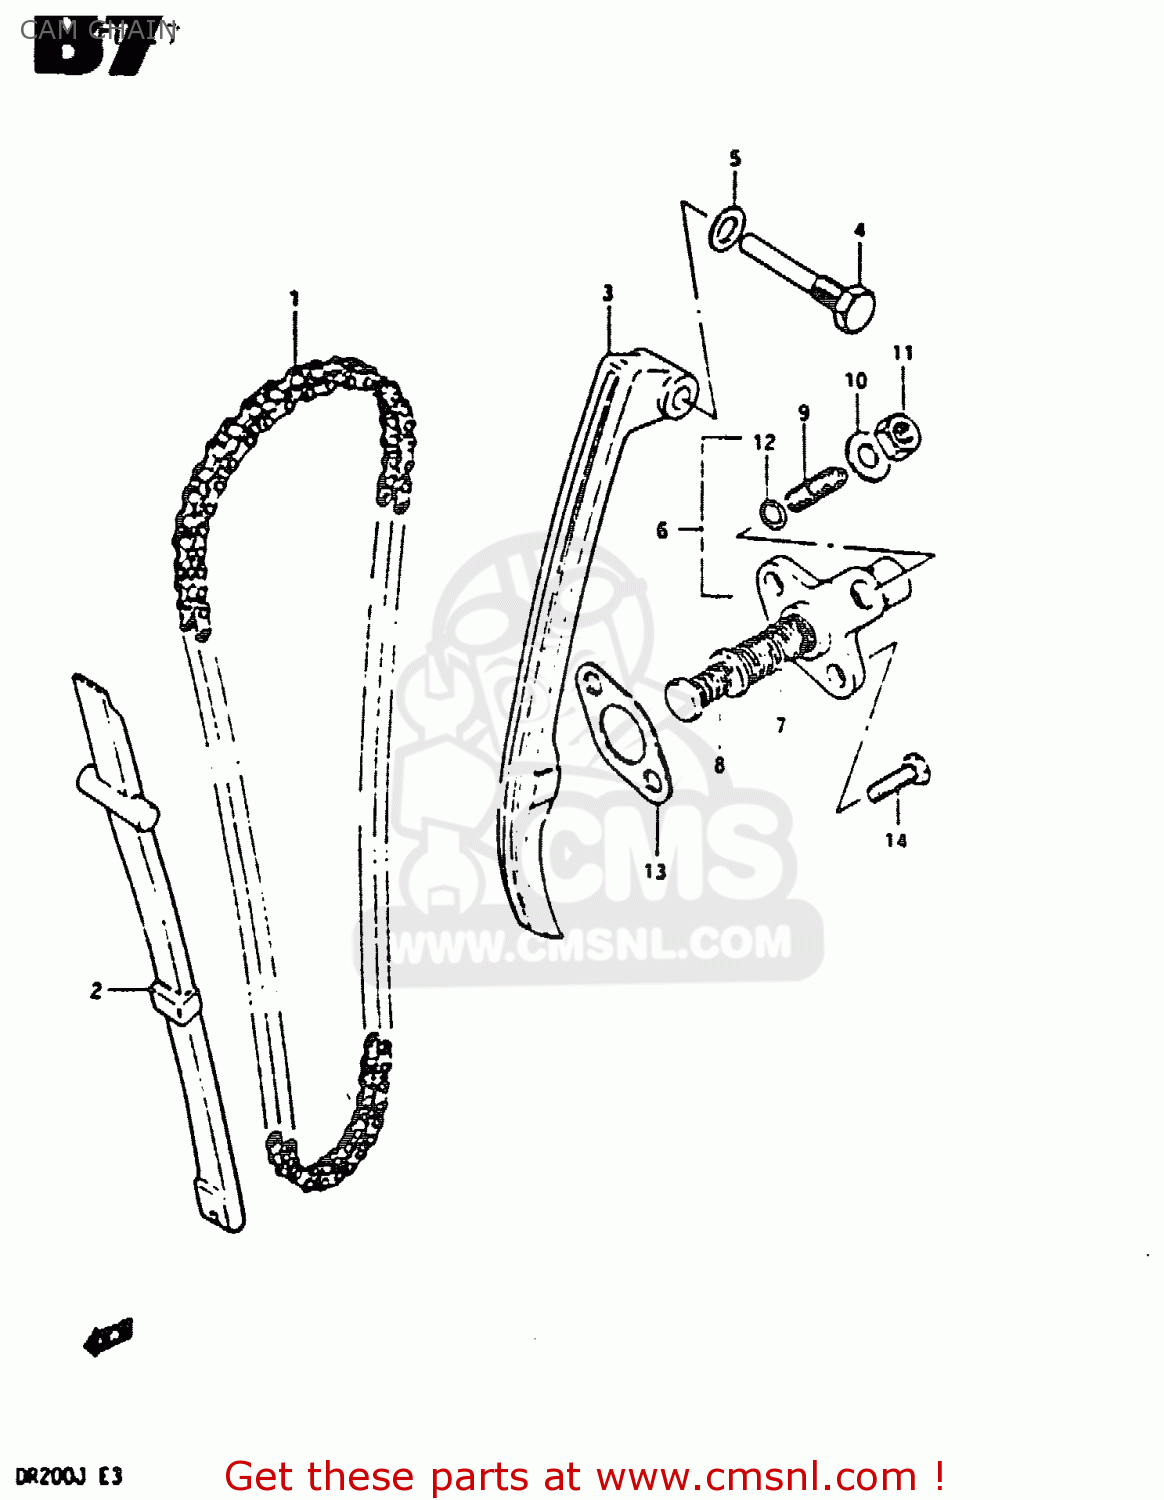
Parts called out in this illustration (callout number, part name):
1	CHAIN,CAMSHAFT DRIVE 102L
2	GUIDE,CAM CHAIN
3	TENSIONER,CAM CHAIN
4	BOLT,CAM CHAIN TENSIONER
5	GASKET 8.2X14X1 (NAS)
6	ADJUSTER ASSEMBLY,TENSIONER
7	SPRING
8	SPRING
9	SCREW
10	WASHER
11	NUT
12	O RING(D:1.9,ID:5.7)
13	GASKET,TENSIONER ADJUSTER (NAS)
14	BOLT
